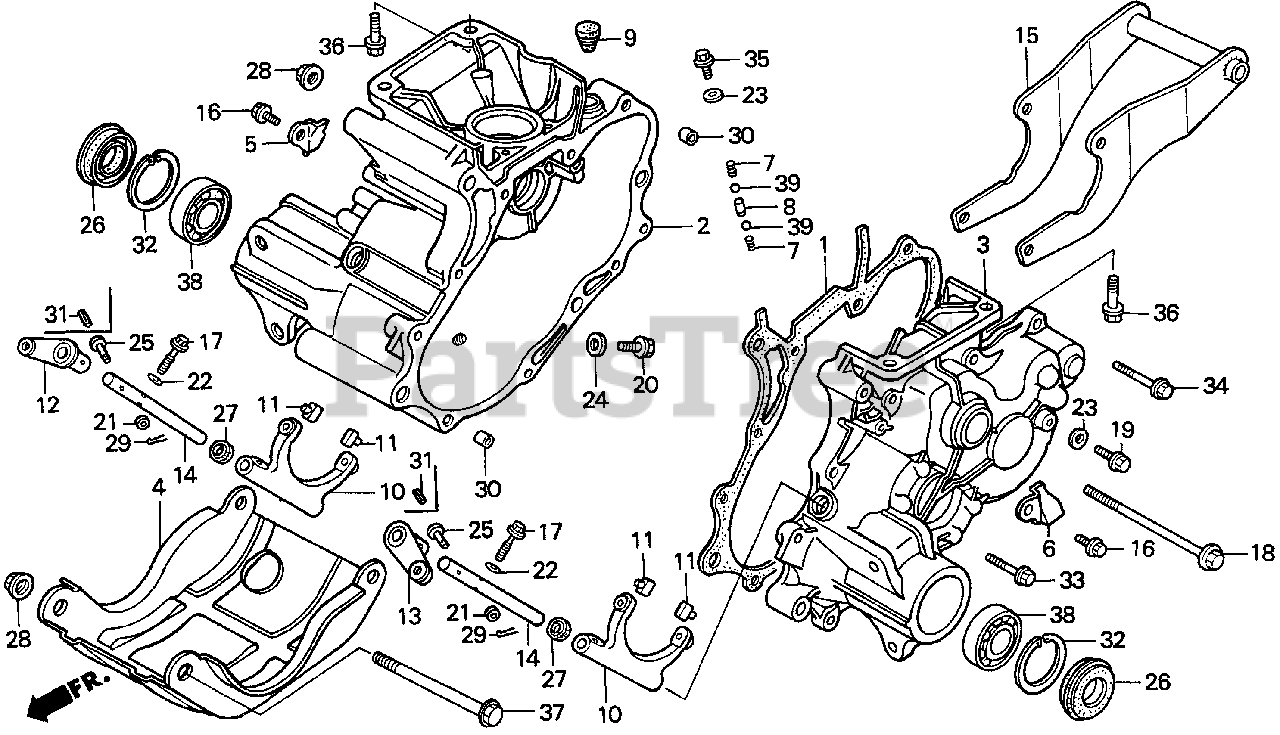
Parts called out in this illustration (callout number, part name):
1	GASKET, TRANSMISSION
2	CASE, R. TRANSMISSION
3	CASE, L. TRANSMISSION
4	PROTECTOR, TRANSMISSION CASE
5	PLATE, R. SIDE CLUTCH
6	PLATE, L. SIDE CLUTCH
7	SPRING, BALL SETTING
8	PIECE, INTERLOCK
9	CAP, TRANSMISSION OIL
10	FORK, SIDE CLUTCH
12	ARM, R. SIDE CLUTCH
13	ARM, L. SIDE CLUTCH
14	SHAFT, SIDE CLUTCH ARM
15	GUARD, TRANSMISSION
16	BOLT, FLANGE (6X12) (CT200)
17	BOLT, HEX. (6X21)
18	BOLT, ALTERNATOR
19	BOLT, FLANGE (8X16)
20	BOLT, DRAIN PLUG
22	WASHER, CONICAL SPRING (6MM)
23	WASHER, SEALING (8MM)
24	WASHER, DRAIN PLUG (10.2MM)
26	OIL SEAL (25X52X9)
27	OIL SEAL (12X18.4.2)
28	NUT, FLANGE (10MM)
30	PIN A, DOWEL (8X14)
31	PIN, SPRING (5X22)
32	CIRCLIP (INNER) (52MM)
33	BOLT, FLANGE (6X32)
34	BOLT, FLANGE (6X40)
35	BOLT, FLANGE (8X16)
36	BOLT, FLANGE (8X28)
37	BOLT, FLANGE (10X125)
38	BEARING, RADIAL BALL (6205)
39	BALL, STEEL (#8) (1/4)
